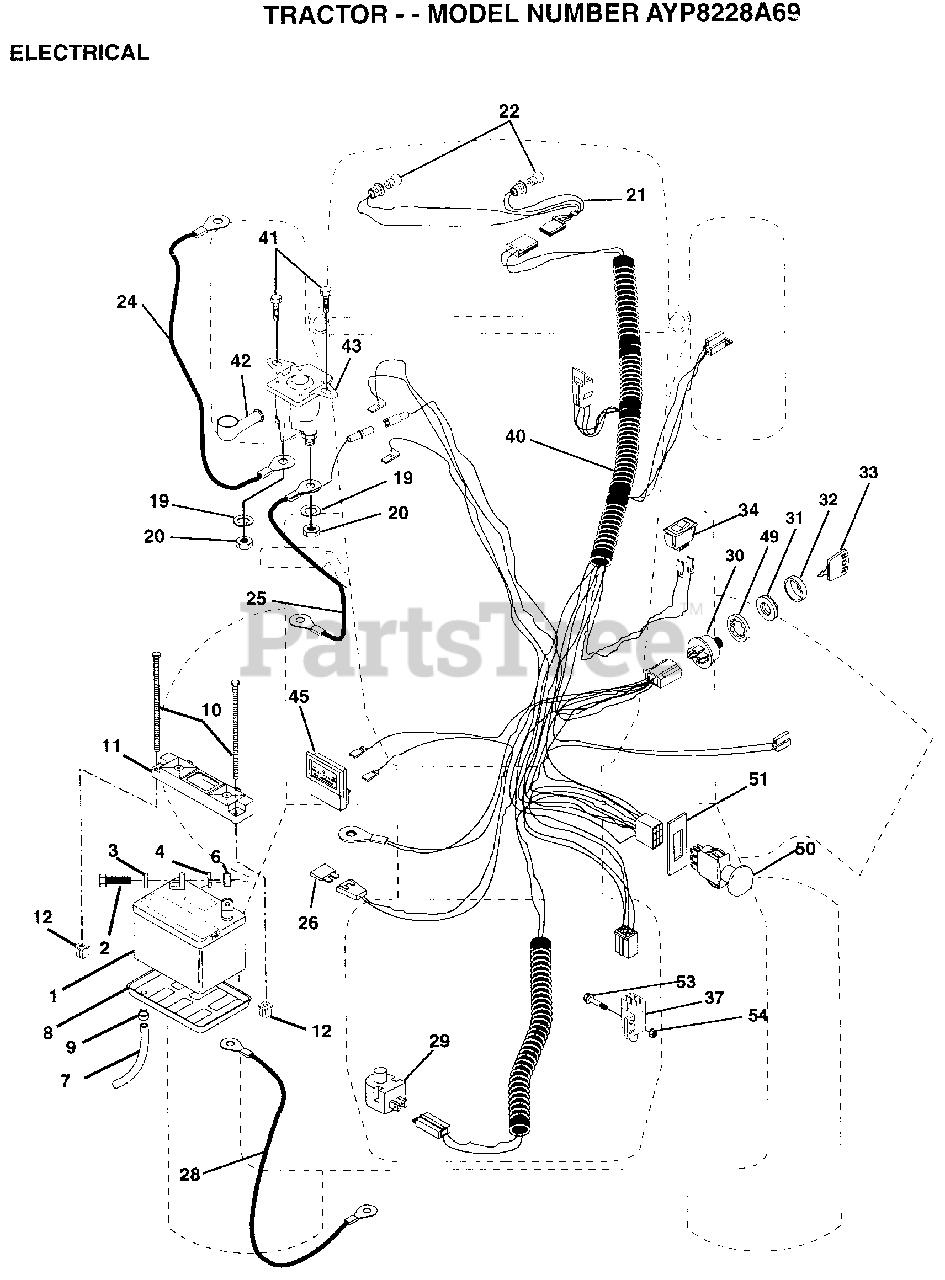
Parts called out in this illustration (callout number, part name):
2	BOLT LT
3	LOCKWASHER
4	WASHER
7	"DRAIN TU T, BATT"
8	"TRAY T, BATTERY"
9	HOSE CLAMP T
20	NUT
21	"HARNESS,LIGHT SOC"
22	HEADLAMP BULB
24	CABLE.BATY.22.RED
25	CABLE.BATRY.4GA.
26	FUSE HYT
28	CABLE.BATRY.4GA.
29	SWITCH SEAT
32	COVER KEY SWITCH
33	KEY MLD GEN DELTA
34	SWITCH LT
39	SWITCH INTERLOCKT
40	HARNESS.IGN.95.GT
41	SCREW
45	AMMETER
49	LOCKWASHER
51	RING RETAIN PTO
53	SCREW
54	"NUT,KEPS"
